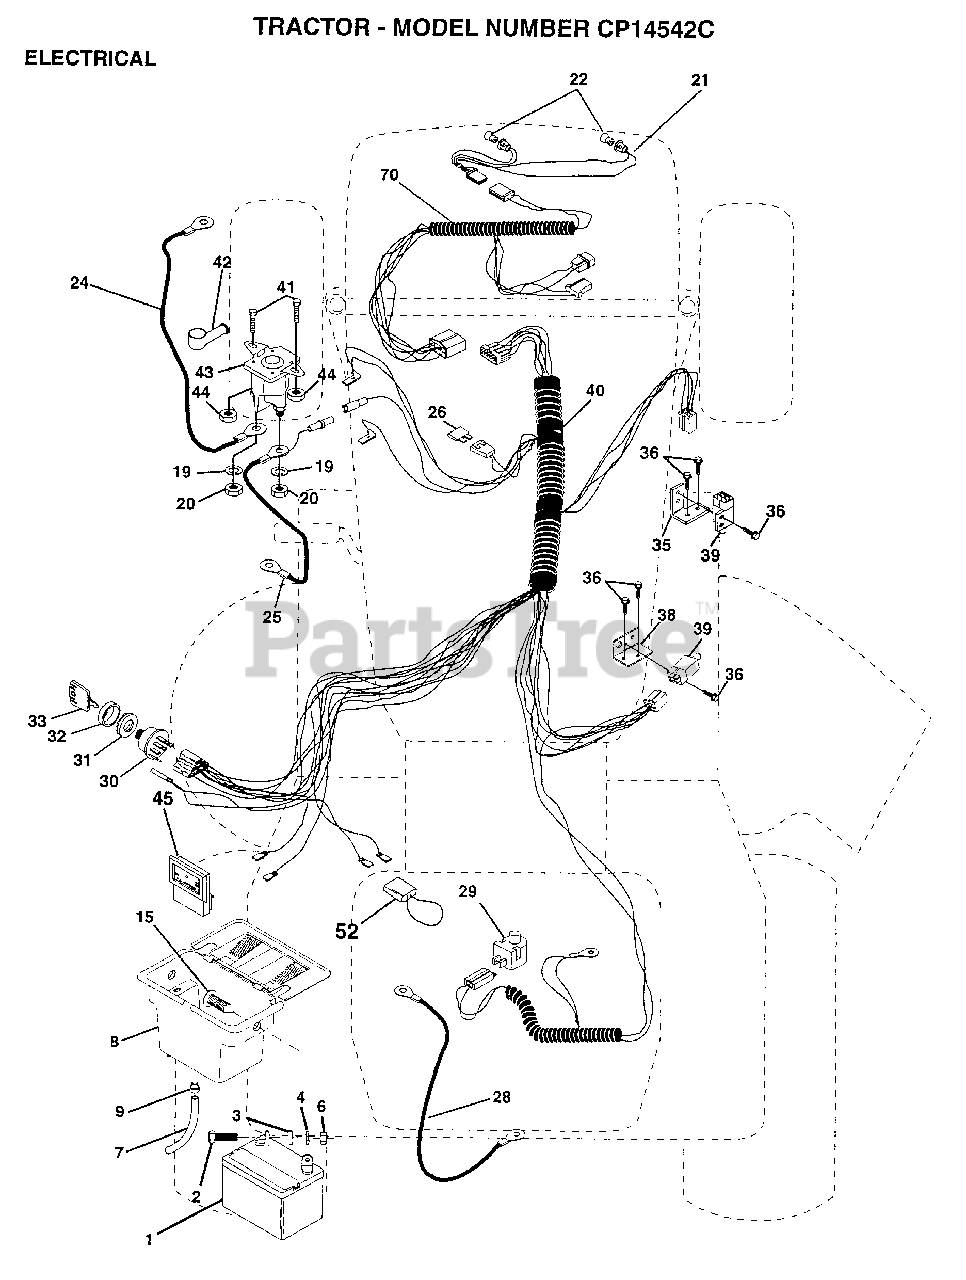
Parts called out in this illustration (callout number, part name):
2	BOLT LT
3	WASHER
4	LOCKWASHER
7	TUBE T
9	HOSE CLAMP T
15	FASTNER.SNAP-IN
20	NUT
21	"HARNESS,LIGHT SOC"
22	HEADLAMP BULB
24	"CABLE T, BATTERY"
25	CABLE.BTRY.6GA.RD
26	FUSE HYT
28	CABLE T
29	SWITCH SEAT
30	SWITCH IGN 4POS
31	NUT IGNITION
32	COVER KEY SWITCH
33	KEY
35	BRACKET LT
36	SCREW
38	BRACKET SWITCH IN
39	SWITCH INTERLOCKT
40	HARNESS.IGNITION
41	BOLT HXHD FIN
44	NUT HXKEP 1/4X20
52	PROTECTION LOOP
70	HARNESS ENGINE
